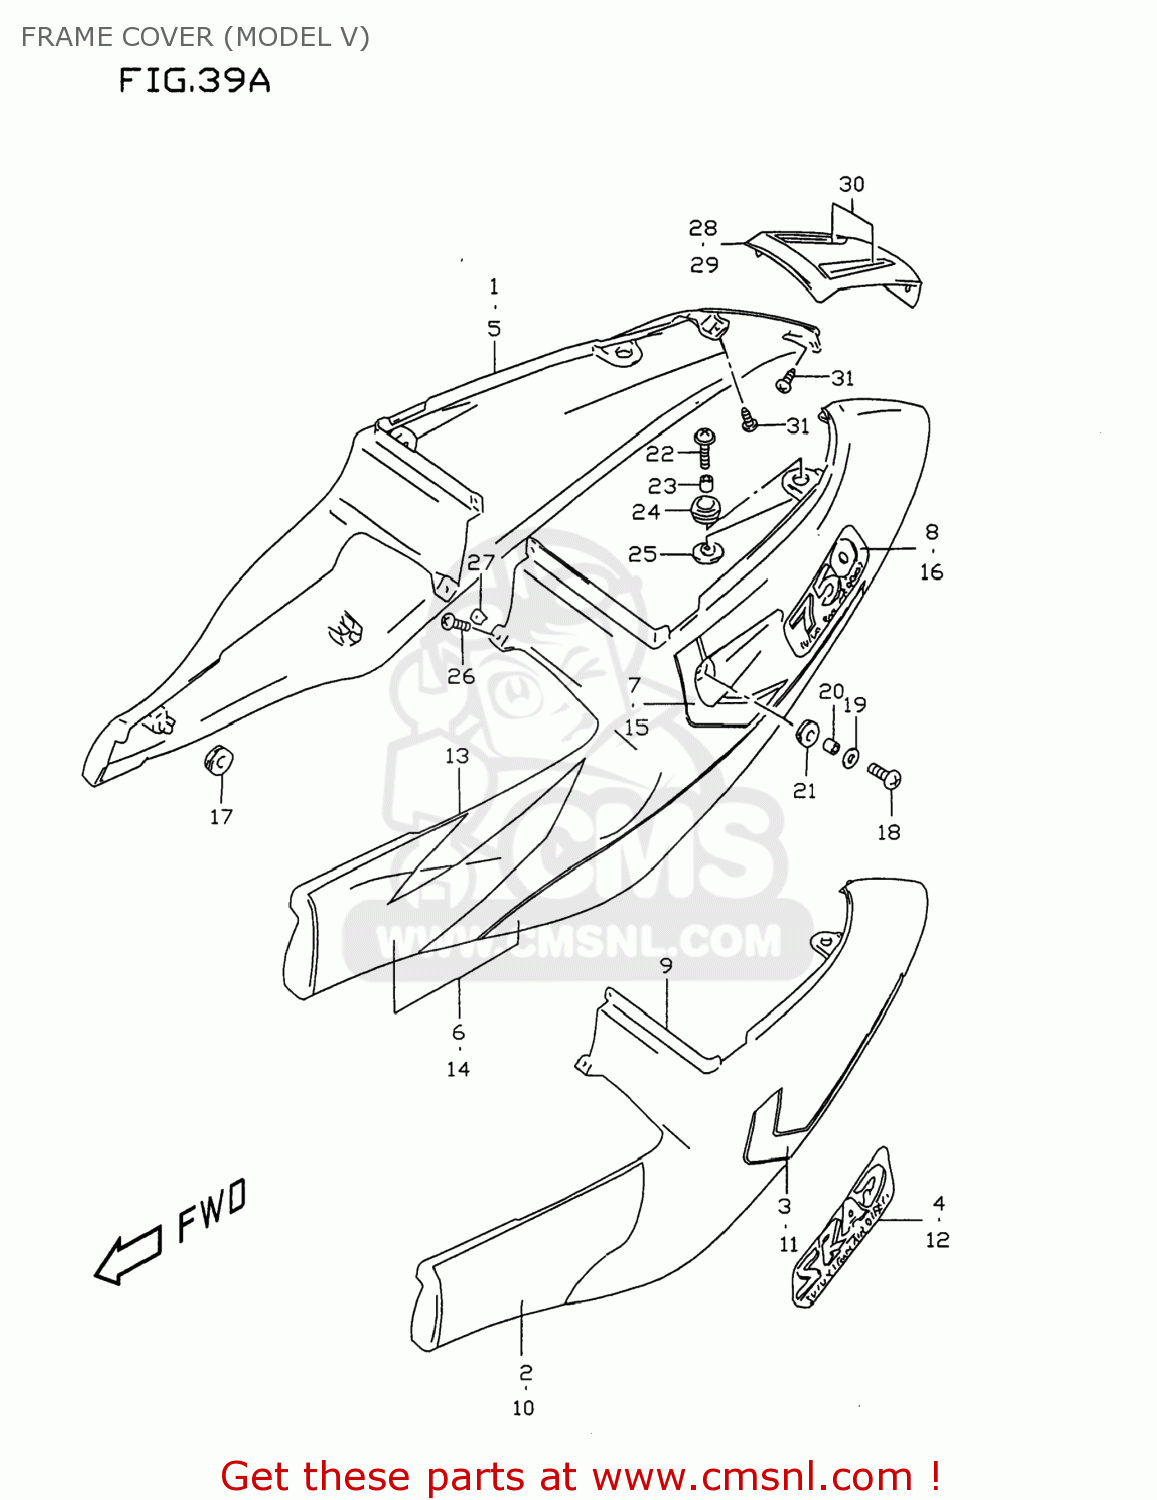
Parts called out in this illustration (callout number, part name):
1	COVER,FRAME,R(ORANGE)
2	TAPE,FRAME COVER,R(BLACK)
3	TAPE,FRAME COVER STRIPE,R
4	EMBLEM,FRAME COVER
5	COVER,FRAME,R(WHITE)
6	TAPE SET,FRAME COVER,R
7	TAPE,FRAME COVER,R
8	EMBLEM,FRAME COVER
9	COVER,FRAME,L(ORANGE)
10	TAPE,FRAME COVER,L(BLACK)
11	TAPE,FRAME COVER STRIPE,L
12	EMBLEM,FRAME COVER
13	COVER,FRAME,L(WHITE)
14	TAPE SET,FRAME COVER,L
15	TAPE,FRAME COVER,LEFT
16	EMBLEM,FRAME COVER
17	CUSHION
18	SCREW(6X20)
19	WASHER(6.5X22X1.6)
20	SPACER(6.5X9X6.7)
21	CUSHION
22	SCREW(6X25)
23	SPACER(6.5X10X9.4)
24	CUSHION,TAIL COVER UPR
25	CUSHION,FRAME COVER LWR
26	SCREW
27	NUT
28	COVER,FRAME CTR
29	COVER,FRAME CTR
30	TAPE SET,FRAME COVER CTR
31	SCREW
